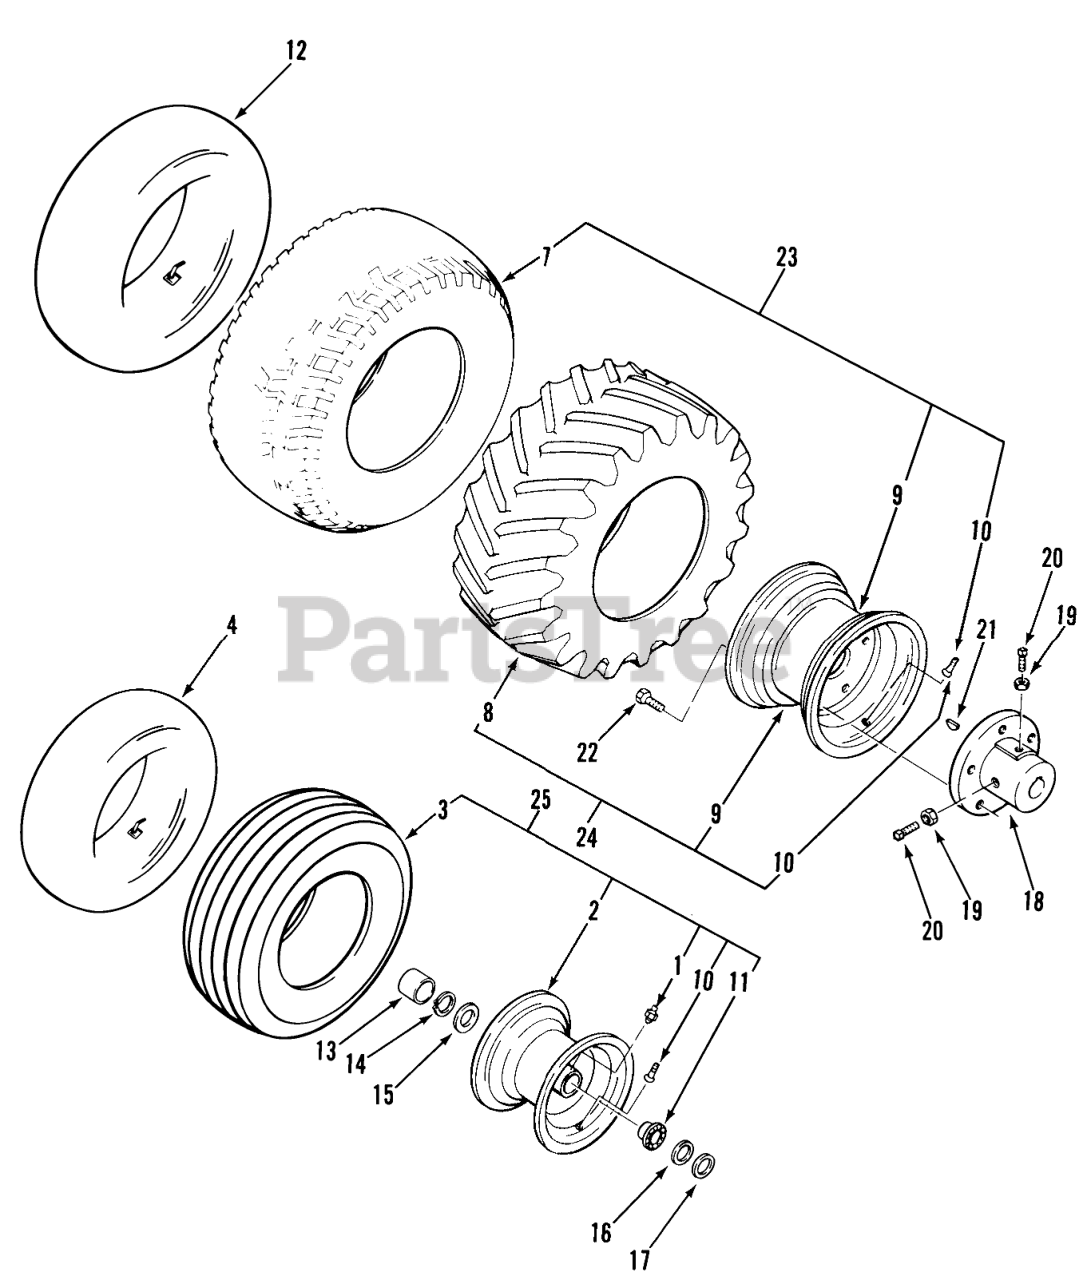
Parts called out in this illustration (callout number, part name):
1	Zerk
2	Front Wheel (Includes Item 1, 10, 11)
3	Front Tire 16 x 6.50-8
4	TUBE-INNER
7	Rear Tire 23 x 10.50-12 GT-1800 Only
7	Tire
7	TIRE 9.50 X 12
8	Tire-Cleat, Rear
9	WHEEL RIM
9	Rear Wheel GT-1100, GT-1600 Only
10	VALVE
11	Bearing
12	Rear Tube
12	TUBE-INNER
13	HUB CAP-FLAT BLACK
14	Snap Ring
15	WASHER-WHEEL
16	WASHER
17	WASHER-SHIM
18	Hub Rear
18	Hub-Rear
19	Nut
20	Screw-Set
21	KEY-WOODRUFF
22	Lug Nut
23	Rear Wheel and Tire Assy Turf GT-1848 Only
23	Rear Wheel and Tire Assy Turf GT-1142 Only
23	Rear Wheel and Tire Assy Turf GT-1642 Only
24	Right Rear Wheel and Tire Assy-Cleat
24	Left Rear Wheel and Tire Assy-Cleat
25	Front Wheel and Tire Assy
